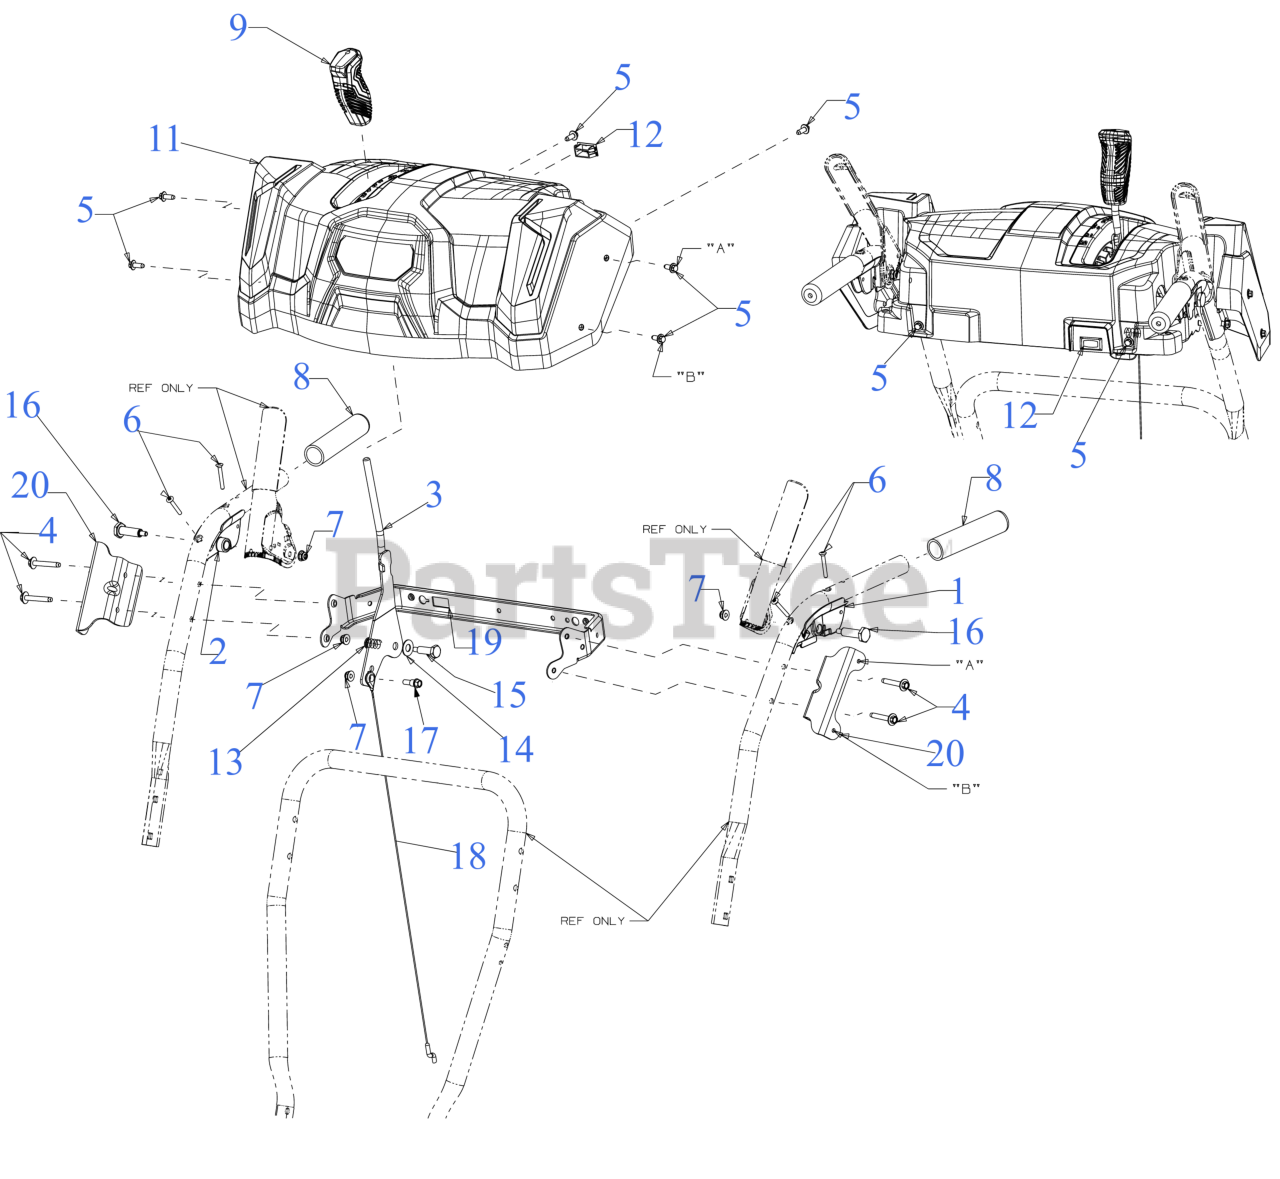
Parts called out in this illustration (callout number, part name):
1	CLUTCH LOCK HANDLE ASSEMBLY (LH)
2	CLUTCH LOCK HANDLE ASSEMBLY (RH)
4	SCREW 1/4-20 x 1.625
5	SCREW M6-1 x .625
6	SCREW #10-24 x 1.375
7	FLANGE LOCK NUT
11	HANDLE PANEL
12	SWITCH PLUG
13	COMPRESSION SPRING
14	FLAT WASHER
15	SHOULDER SCREW
16	SHOULDER SCREW .437 x 1.345 1/4-20
17	SHOULDER SCREW .342X.335X1/4-20
18	SELECTION CABLE
